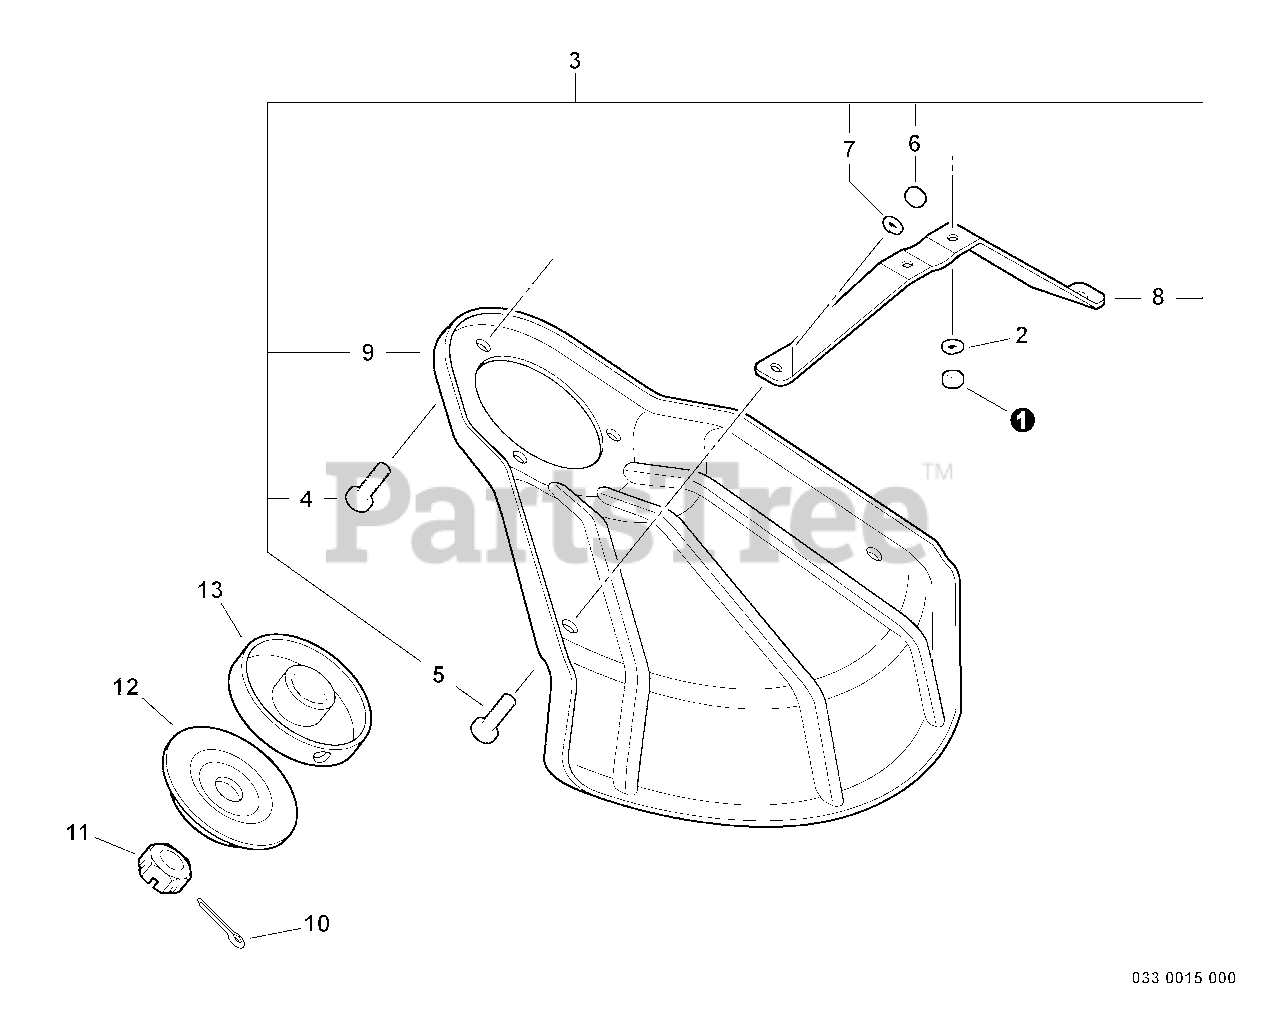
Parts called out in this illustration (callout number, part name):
2	LOCKWASHER - 5
3	DEBRIS SHIELD KIT - METAL
4	SCREW - 5X10
5	SCREW - 5X8
7	LOCKWASHER - 5
8	BRACKET, SHIELD
9	SHIELD, DEBRIS - METAL
10	PIN, SPLIT - 2X22
11	LOCKNUT - LEFT HAND
12	ADAPTOR, BLADE - LOWER
13	ADAPTOR, BLADE - UPPER
